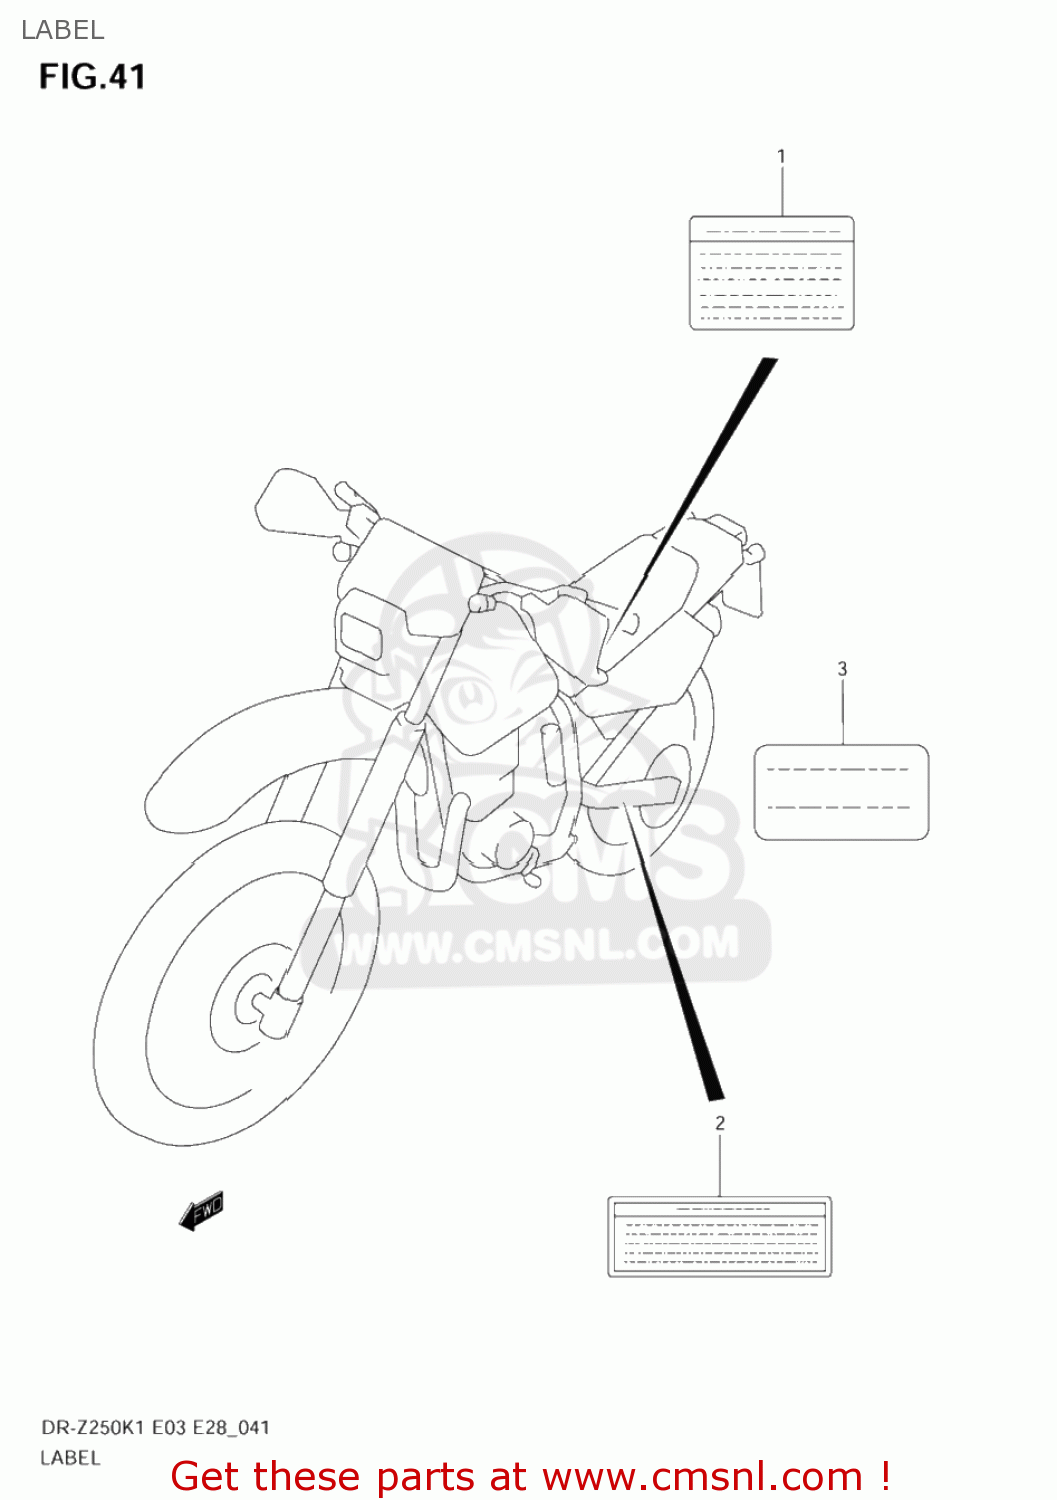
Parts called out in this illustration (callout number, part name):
1	LABEL,GENERAL WARNING
2	LABEL,TIRE AIR PRESSURE
3	LABEL,MANUAL NOTICE
4	MANUAL,OWNER'S
